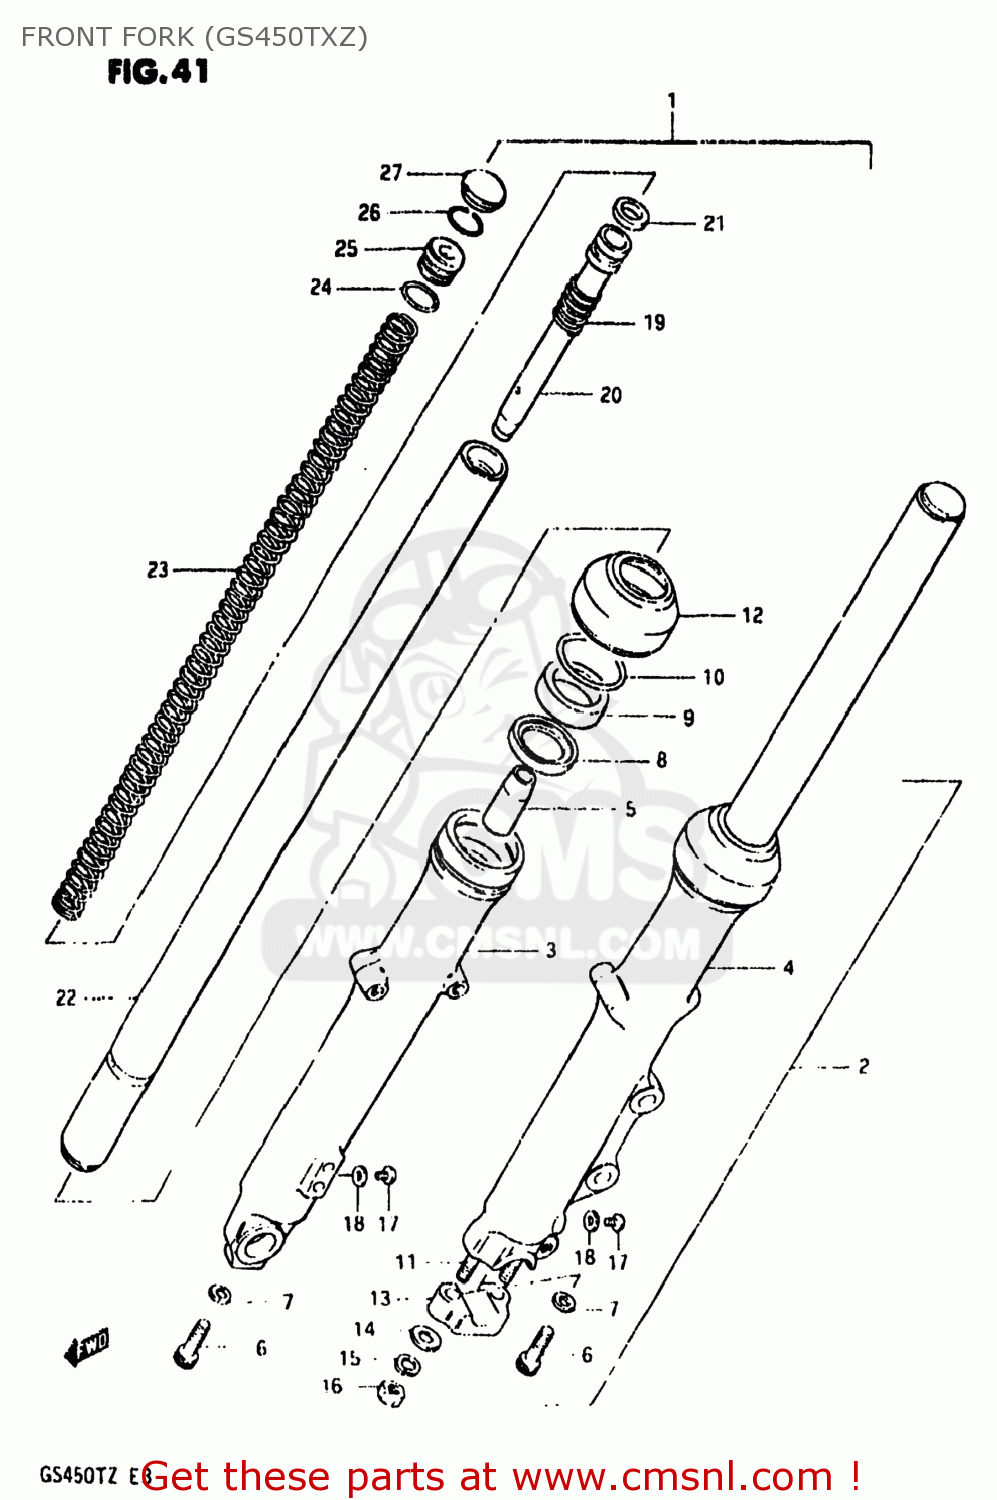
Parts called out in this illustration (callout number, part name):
1	DAMPER ASSEMBLY,RIGHT
2	DAMPER ASSEMBLY,LEFT
3	TUBE,FORK,OUTER,RIGHT
4	TUBE,FORK,LEFT,OUTER
5	PIECE,OIL LOCK
6	BOLT(8X27)
7	GASKET (NAS)
8	SPACER,OIL SEAL
9	OIL SEAL,FRONT FORK
10	CIRCLIP,FORK OIL SEAL
11	STUD 8X25
12	DUST SEAL
13	HOLDER,AXLE
14	WASHER
15	LOCK WASHER
16	NUT (8MM)
17	SCREW 4X6
18	GASKET (NAS)
19	SPRING,REBOUND
20	CYLINDER,FRONT FORK
21	RING,PISTON
22	TUBE,FORK,INNER
23	SPRING
24	O RING
25	SEAT,SPRING
26	RING,STOPPER
27	CAP,FRONT FORK
